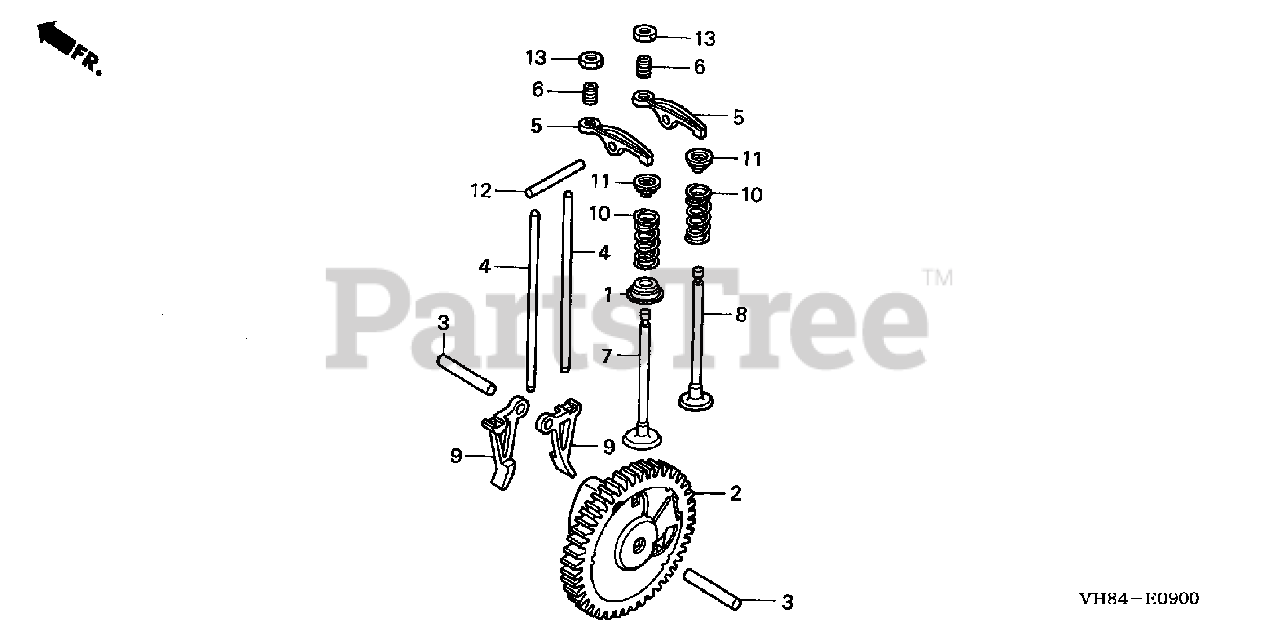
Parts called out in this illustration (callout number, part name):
2	CAMSHAFT ASSY.
3	ROLLER (5X23.8)
5	ARM, VALVE ROCKER
6	PIVOT, ROCKER ARM
7	VALVE, IN.
8	VALVE, EX.
9	LIFTER, VALVE
10	SPRING, VALVE
11	RETAINER, VALVE SPRING
12	ROLLER (4X28)
13	NUT, TAPPET ADJUSTING
